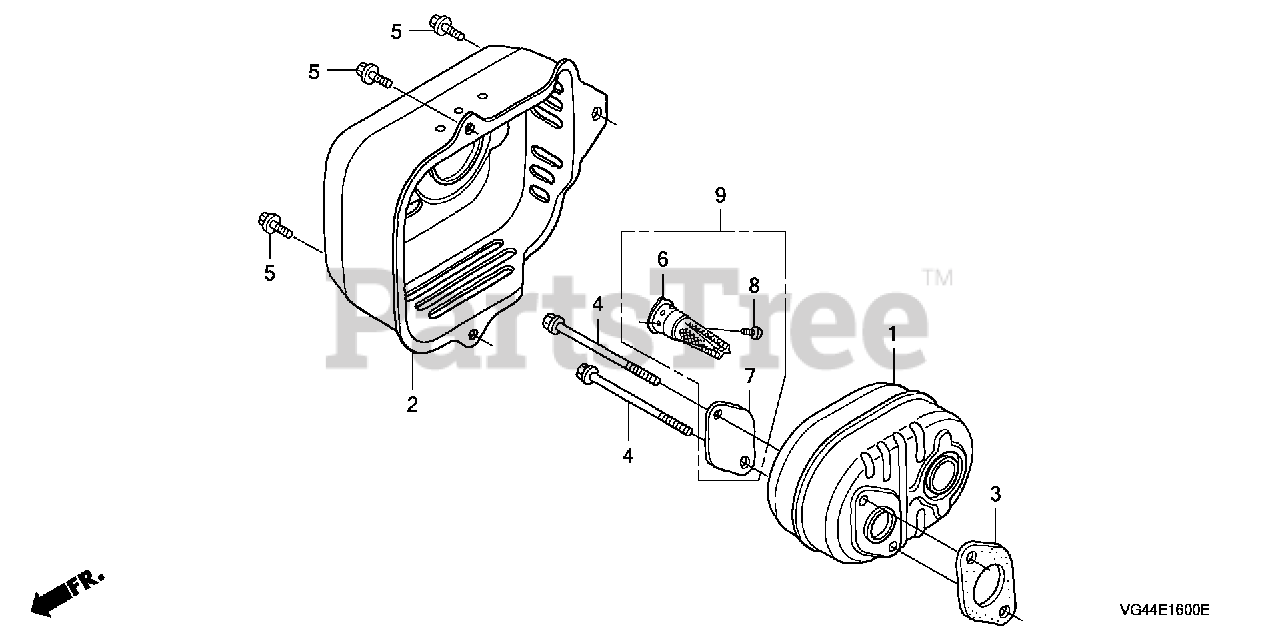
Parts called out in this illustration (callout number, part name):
2	PROTECTOR, MUFFLER
3	GASKET, MUFFLER
4	BOLT, FLANGE (6X79) (CT200)
5	BOLT, FLANGE (6X12) (CT200)
6	ARRESTER, SPARK (OPTIONAL)
7	PLATE, ARRESTER NUMBER (TO INSTALL OPTIONAL SPARK ARRESTER)
8	SCREW, TAPPING (4X6) (TO INSTALL OPTIONAL SPARK ARRESTER)
9	ARRESTER KIT, SPARK
